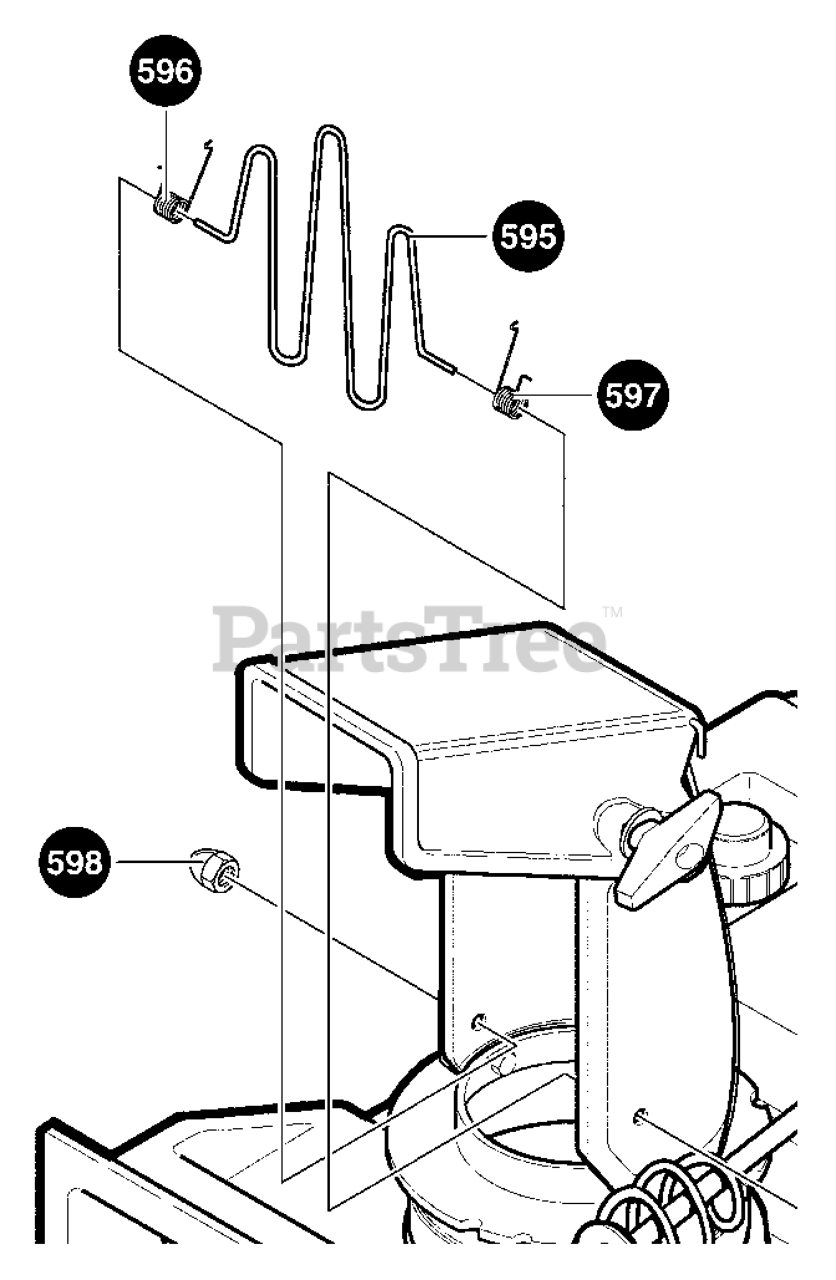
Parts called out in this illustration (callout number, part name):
595	GUARD, WIRE CHUTE
596	SPRING, TORSION
597	SPRING, TORSION
598	NUT, ACORN
